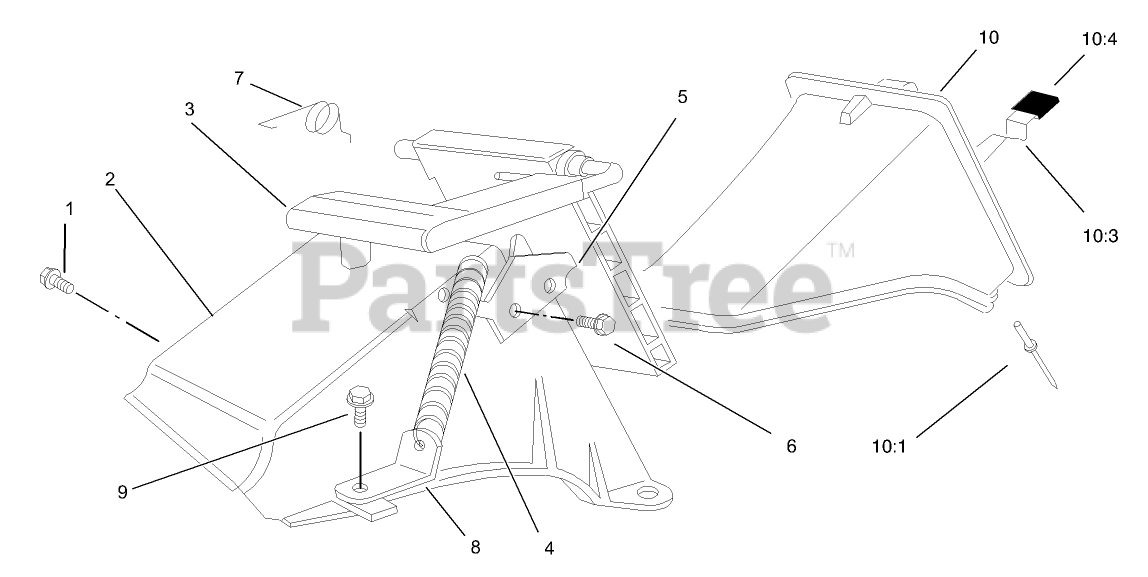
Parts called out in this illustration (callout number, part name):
1	SCREW AND WASHER ASM
2	TUNNEL-DISCHARGE
3	DISCHARGE DOOR ASM
4	SPRING-DOOR
5	LATCH-PLATE
6	SCREW-PLASTITE
7	RETAINER-DOOR
8	BRACKET-SPRING
9	SCREW-HWH
10	DISCHARGE PLUG ASM
10:1	RIVET-HEAD, FLAT
10:3	LATCH-PLUG, DISCHARGE
10:4	GRIP-LATCH
